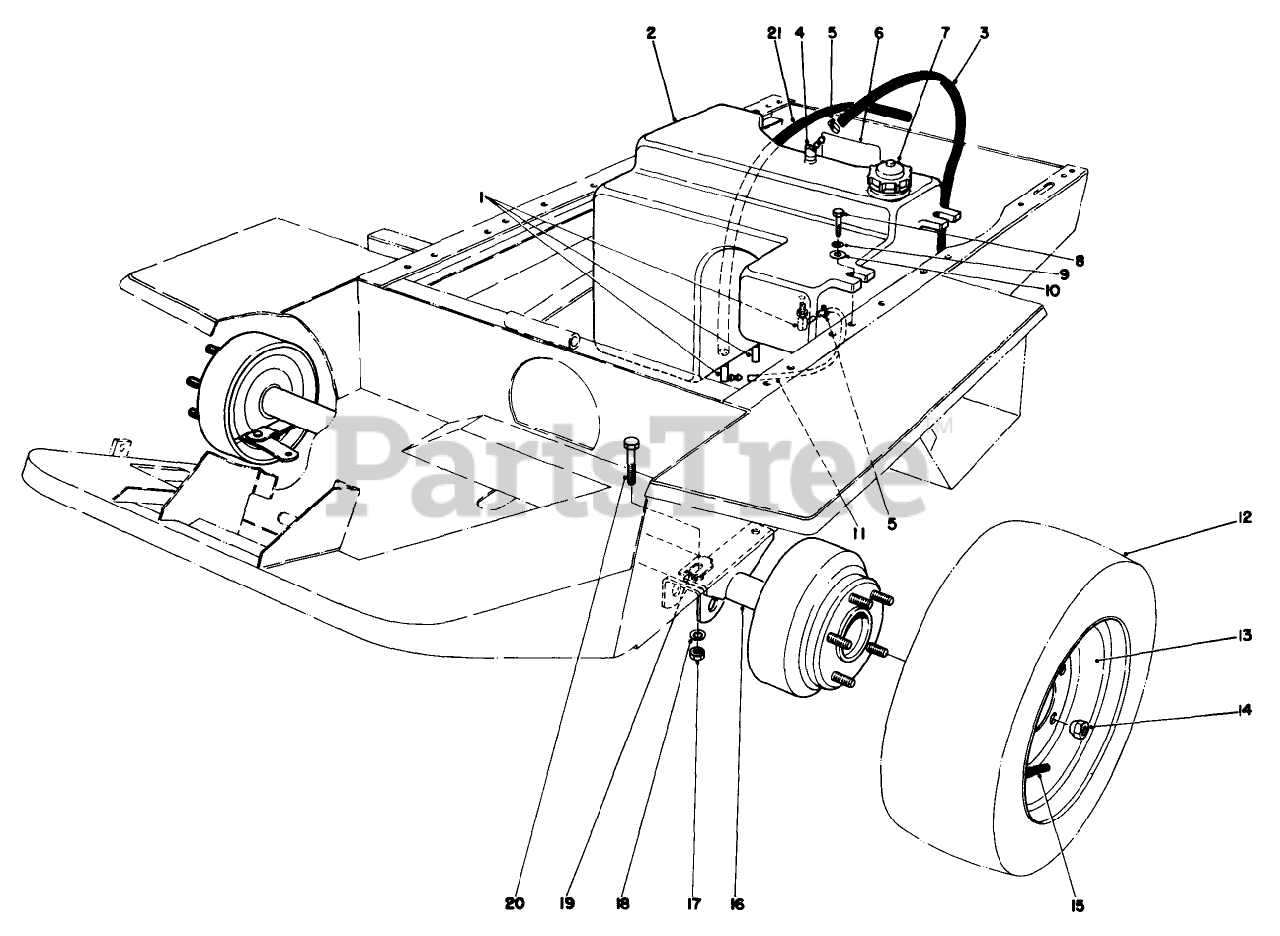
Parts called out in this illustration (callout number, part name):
1	FITTING-ELBOW, 90 DEG
2	Tank-Gas (Incl. Ref. #1 & 3)
3	GAS TANK VENT HOSE
4	ELBOW
5	CLAMP-HOSE
6	DECAL-DANGER
7	GAS CAP ASSEMBLY
8	SCREW-HH
9	WASHER-LOCK
10	WASHER
11	Hose-Fuel
12	20 X 8.00 - 10 TIRE
13	WHEEL ASM
14	NUT-WHEEL
15	VALVE STEM AND CAP ASM
16	Assembly-Axle
17	NUT-HEX
18	WASHER-LOCK
19	SHIM-AXLE
20	SCREW-HH
21	HOSE
